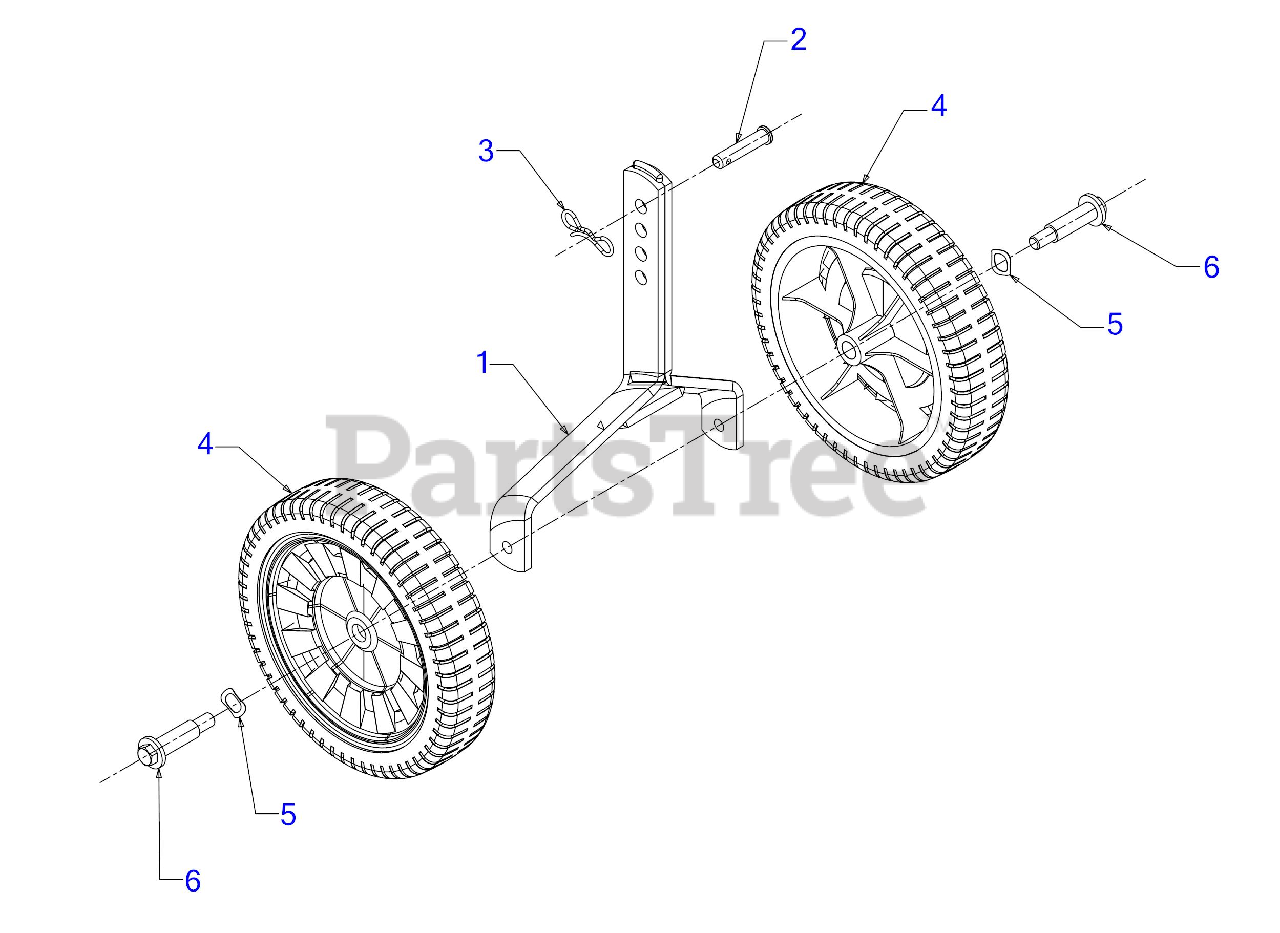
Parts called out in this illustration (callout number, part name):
1	WHEEL BRACKET ASSEMBLY
2	CLEVIS PIN .375 x .1.75
3	PIN:COTTER
4	WHEEL-8IN
5	WAVE WASHER
6	SHOULDER SCREW .496X1.44 3/8-16
